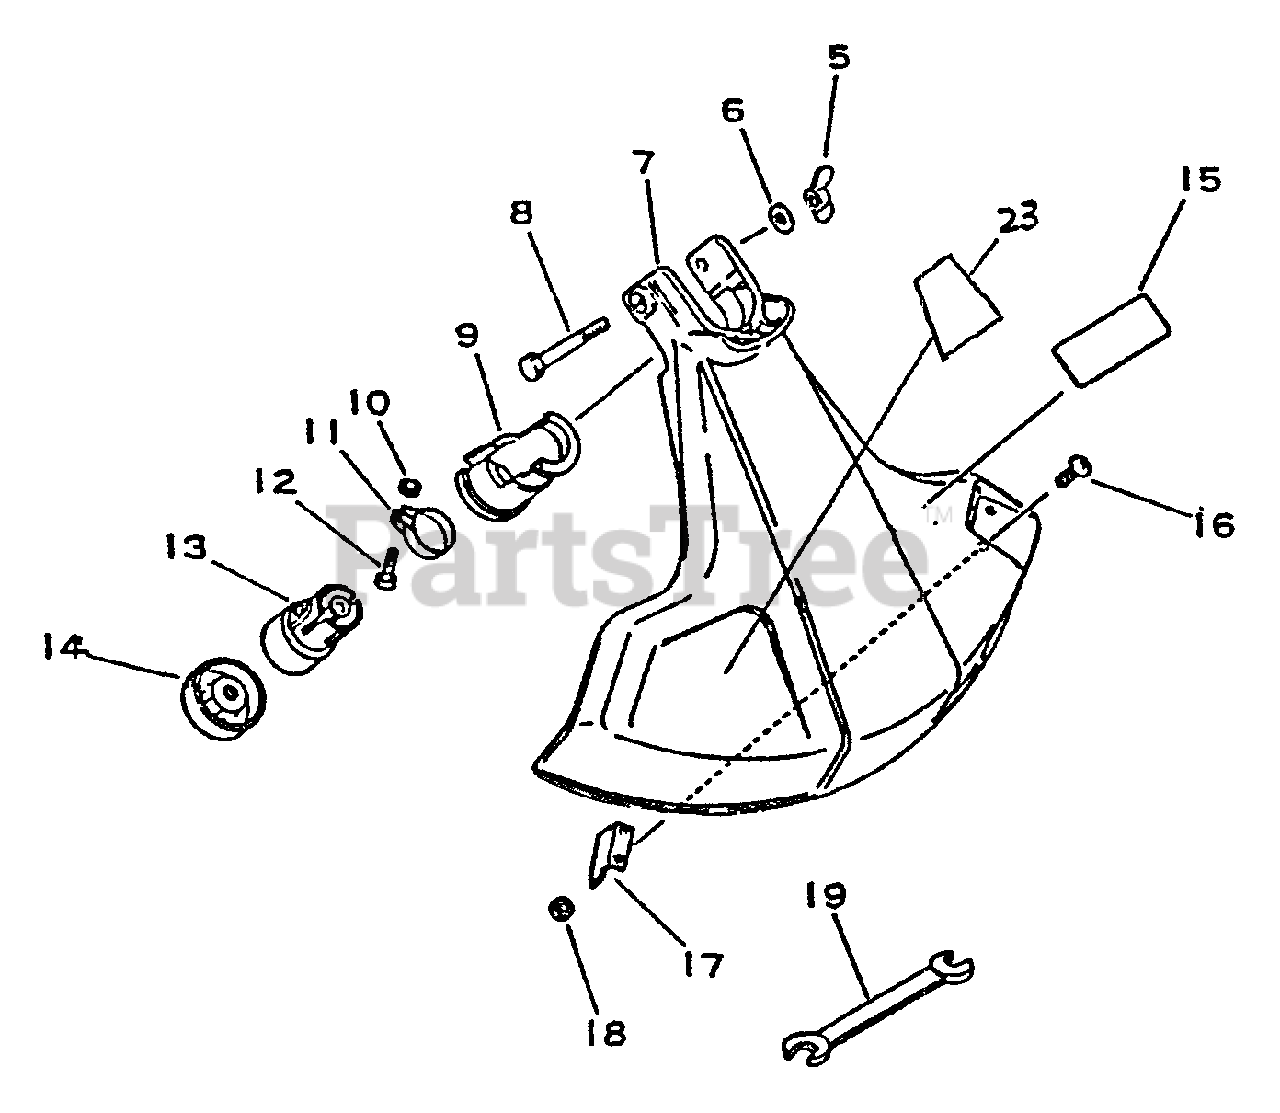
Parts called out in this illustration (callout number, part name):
5	WINGNUT - 6
6	WASHER - 6
7	SHIELD, DEBRIS - PLASTIC
8	BOLT - 6X50
9	BRACKET, BEARING CASE
13	GEAR CASE ASSY
14	ADAPTOR, BLADE - UPPER
15	LABEL - ECHO
16	SCREW - 5X16
17	KNIFE, TRIMMER LINE
19	SPANNER - 8X10mm
23	LABEL - CAUTION
